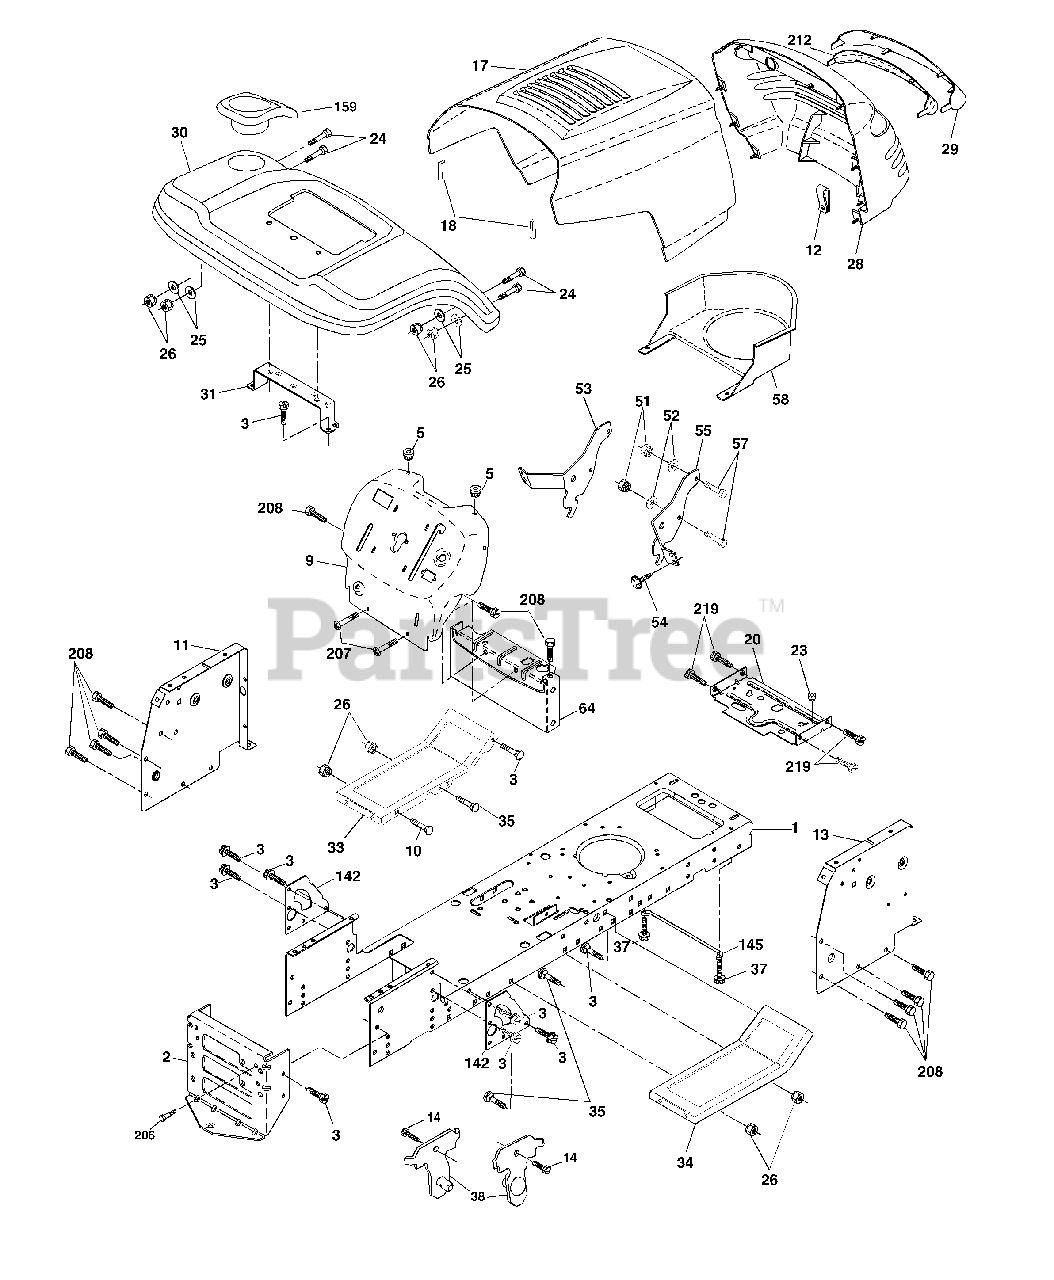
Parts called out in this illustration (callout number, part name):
1	Chassis stamping
2	Drawbar, 12 Ga.
3	Screw 3/8-16x3/4
5	Bumper Hood/Dash
9	Dash Slkscr
10	Bolt Carriage 3/8-16 x 1
11	Panel Dash Lh
12	Clip Tinnerman
13	Panel Dash Rh
14	Screw Thdrol 3/8-16 x 1/2
17	Hood LT/PL
18	Bumper Hood
20	Plate Mtg Battery Fuel Tank Fr
24	Bolt Fin Hex 3/8-16 Unc x 1 Gr. 5
25	Washer 13/32 X 13/16 X 12 Ga
26	Nut Lock Hex w/Ins. 3/8-16 Unc
28	Grille/Lens Asm
29	Lens
30	Fender
31	Bracket Fender
33	Footrest Pnt Lh
34	Footrest Pnt Rh
35	Bolt Rdhd Sht Sqnk 3/8-16 x 3/4
37	Screw Thdrol 6/16-18 x 1/2 TYT
38	Bracket Asm Pivot Mower Rear
51	Nut Lock w/Insert 1/4-20 Unc
52	Washer 9/32 x 7/8 x 16 Ga.
53	Bracket Grille Lh
54	Screw Hex Wsh 8-18 x 7/8
55	Bracket Grille Rh
57	Bolt Hex 1/4-20 x 3/4
58	Air Duct Engine P/L
64	Dash Lower STLT
142	Plate Reinforcement STLT
145	Rod Pivot Chassis/Hood
159	Cupholder Stlt Grey
206	Bolt Shoulder 5/16-18 TT
207	Screw Thdrol 5/16-18 x 1/2
208	Screw Thdrol 3/8-16 x 1/2
212	Insert Lens Reflective
219	Screw 5/16-18 x 3/4
